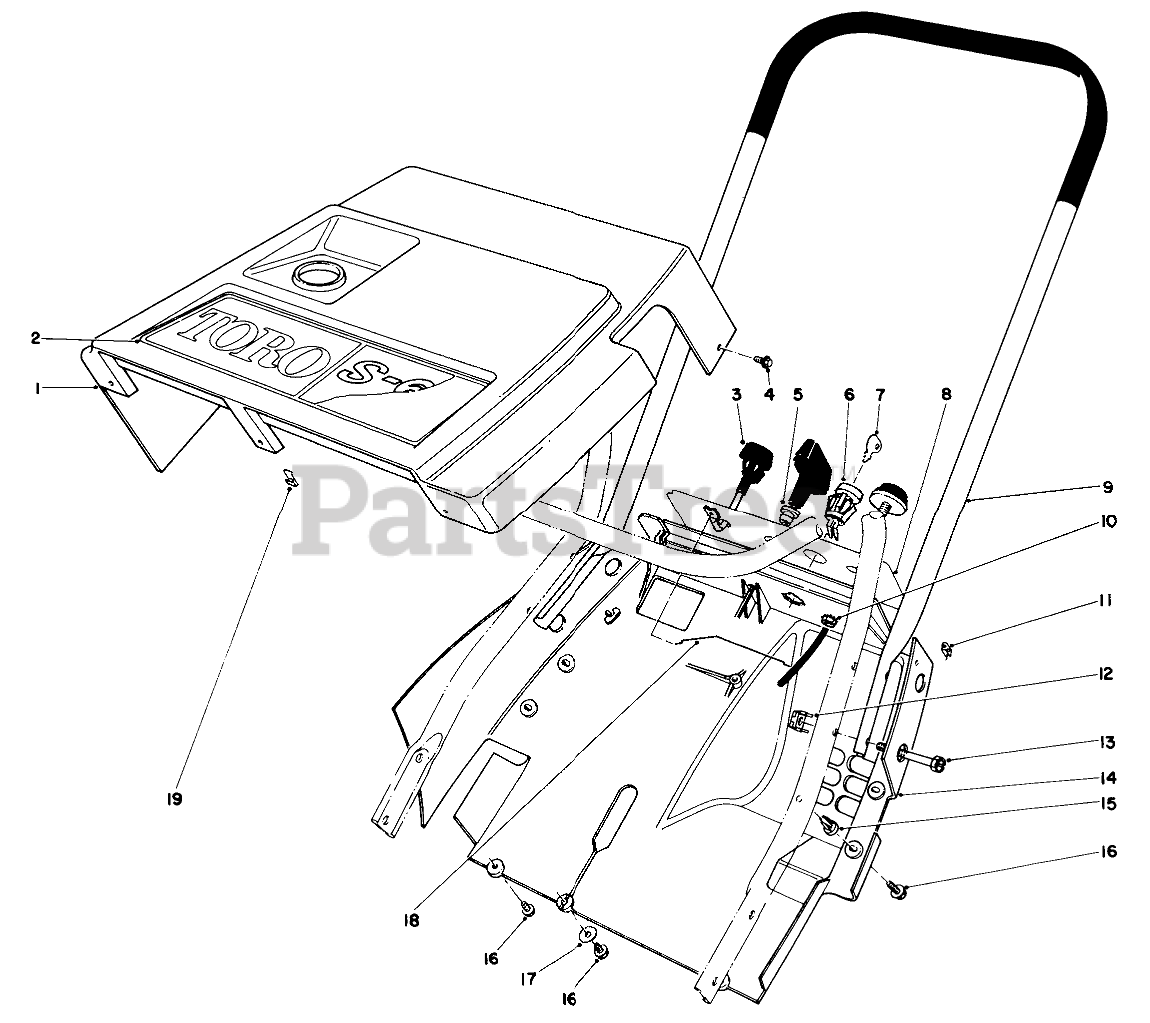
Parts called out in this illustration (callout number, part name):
1	Shroud-Upper
2	TORO DECAL
3	CHOKE CONTROL ASM
4	SCREW-HWHTF
5	GUIDE-ROPE, STARTER
6	SWITCH
7	KEY-IGNITION
8	Decal-Control Panel
9	Handle-Upper
10	NUT-KEPS
12	TINNERMAN NUT
13	SCREW-HEX HD SLOT
14	LOWER SHROUD
15	Nut-Push
16	SCREW-HWHTF
17	WASHER-FLAT
18	CONTROL WIRE
19	NUT "U"
